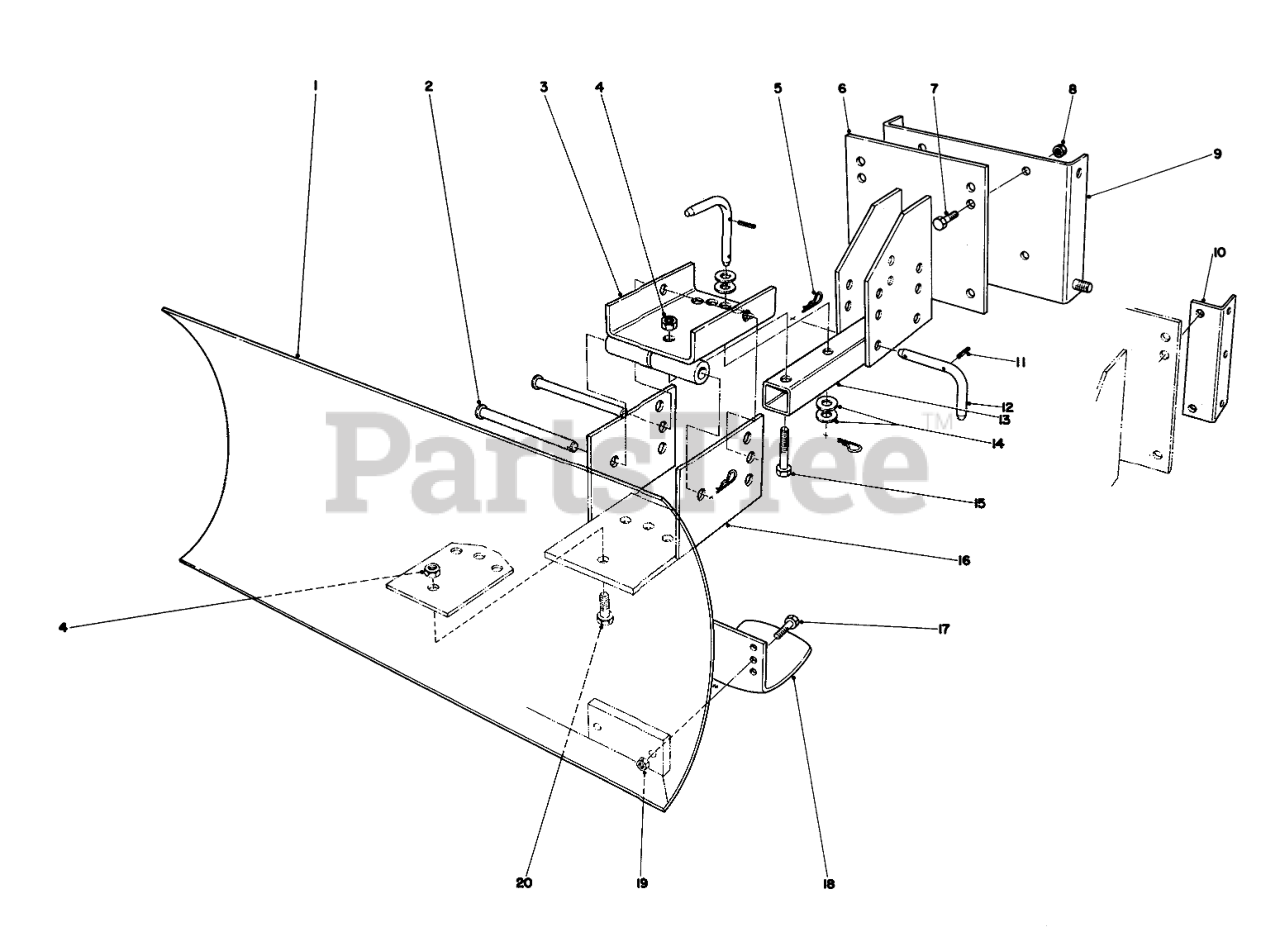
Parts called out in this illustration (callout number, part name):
1	Blade
2	PIN-CLEVIS
3	Swivel Bracket
4	1/2-13 CONELOCK NUT
5	PIN-HAIR
6	Mounting Plate
7	Capscrew
8	NUT-LOCK, CONE
9	Mounting Plate (Used with 826 & 1132 Units only)
10	Mounting Rail (used with 421 units only)
11	PIN-SPRING
12	Pivot Pin (Incl. Ref. #11)
13	Blade Tongue
14	WASHER-FLAT
15	SCREW-HH
16	Blade Adjustment
17	SCREW-HH
19	NUT-LOCK, CONE
20	SCREW-HH
